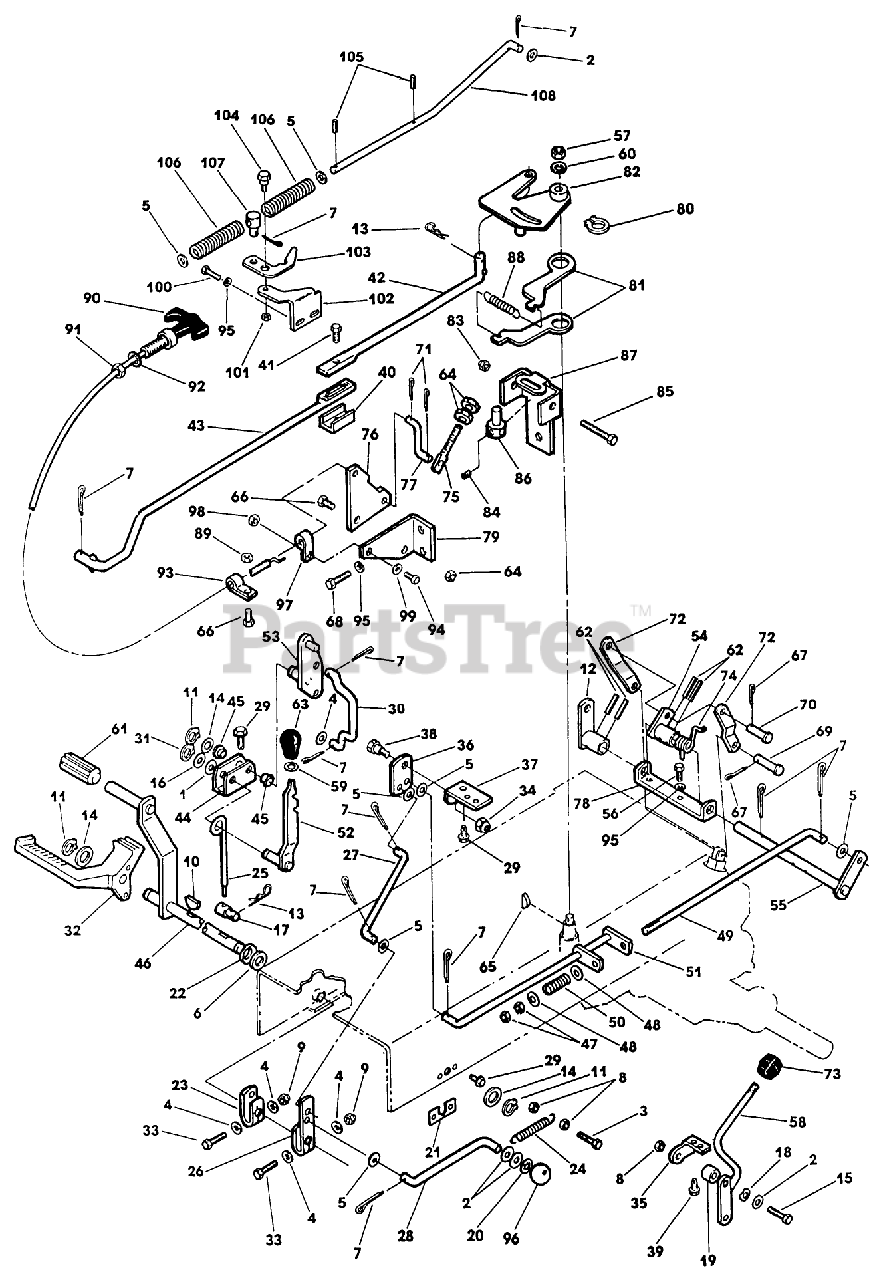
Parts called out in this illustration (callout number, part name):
4	WASHER
8	NUT
9	NUT-LOCKING
13	PIN-HAIR
14	WASHER
15	SCREW
22	WASHER-CUPPED
31	RING - RETAINING
34	NUT
37	BRKT-BRAKE PIVOT
40	CLAMP
50	SPRING-BRAKE
52	CRUISE RELEASE AY.
56	SCREW - HEX
57	NUT
60	WASHER
66	SCREW
68	SCREW-THD ROLL, HWH
74	SPRING,TORSION
76	LEVEL - PIVOT
79	BRACKET,CABLE
80	RING - RETAINING
84	SETSCREW
88	SPRING-EXTENSION
89	NUT-LOCK, CONE
91	Nut, Hex Jam
102	BRACKET-LOCK
104	BOLT-SHOULDER
